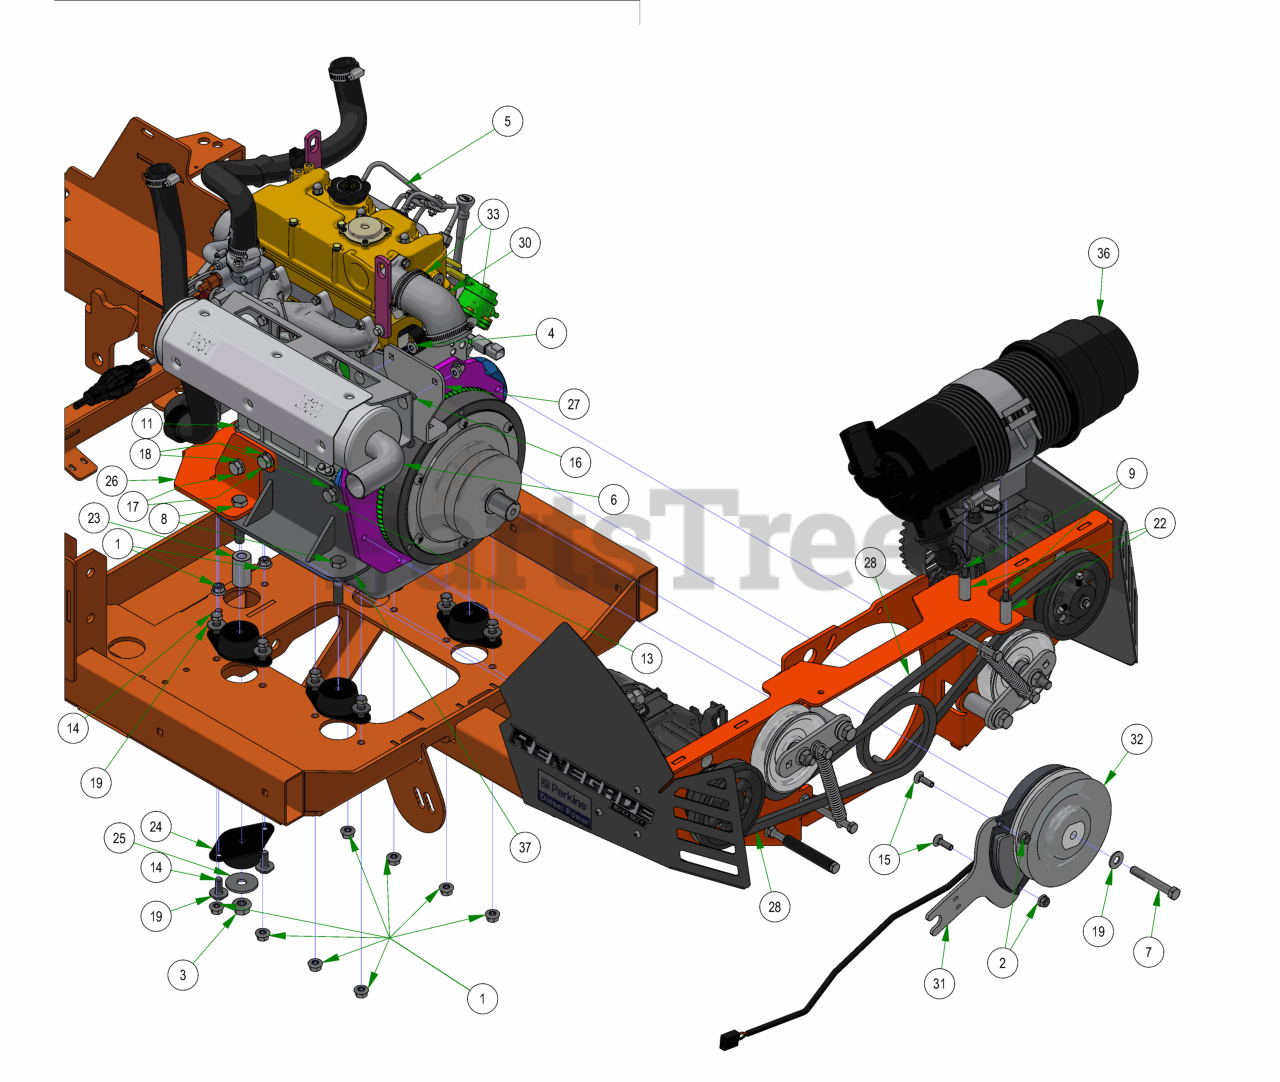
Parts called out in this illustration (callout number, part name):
1	3/8-16 NYLON INSERT FLANGE LOCKNUT (GR.F) ZINC
2	5/16-18 NYLON INSERT FLANGE LOCKNUT ZINC
3	1/2-13 NYLON INSERT FLANGE LOCKNUT ZINC
4	5/16-18 HEX SERRATED FLANGE NUT HARD/ZINC
5	24.7HP Perkins Engine, 403J-11
6	2019 Renegade 1100cc Diesel Muffler
7	7/16-20x3” Hex Bolt GR 8 W/ Patch
8	1/2-13 X 2-1/2 HEX CAP SCREW GR 5 ZINC
9	5/16-18 X 2-1/4 HEX CAP SCREW (GR.5) ZINC
11	1/2-13 X 4 HEX CAP SCREW (GR.8) ZINC YELLOW
13	M12-1.25 X 25MM DIN 961 HEX TAP BOLT (CL 8.8) ZINC
14	3/8-16 X 1 GR 5 Hex Bolts Zinc
15	5/16-18 X 1 CARRIAGE BOLT (GR.8) ZINC
16	5/16-18 X 7/8 CARRIAGE BOLT ZINC
17	M12-1.25 X 30MM DIN 961 HEX TAP BOLT (CL 8.8) ZINC
18	1/2 SPLIT LOCKWASHER (GR.8) ZINC/YELLOW
19	3/8 FLAT WASHER USS (1" OD) ZINC
22	.380 ID X .625 OD X 1.500 LGTH 2019 OUTLAW BRAKE HANDLE SPACER ZINC
23	1 3/4" Pulley Spacer
24	Rubber Compression Mount
25	.520 ID X 1.750 OD X .120 THICK FLAT WASHER ZINC
26	2022 Renegade Diesel Front Engine Mount
27	2019 Diesel Muffler Bracket
28	2020 Renegade Pump Belt, 42.99"
30	2019 Diesel Air intake Hose
31	2019 Outlaw Renegade Clutch Bracket
32	Clutch for Diesel/Vanguard
33	2-1/2" Hose Clamp
36	Enginaire Canister VLR-Complet
37	2019 Diesel Motor Mount
